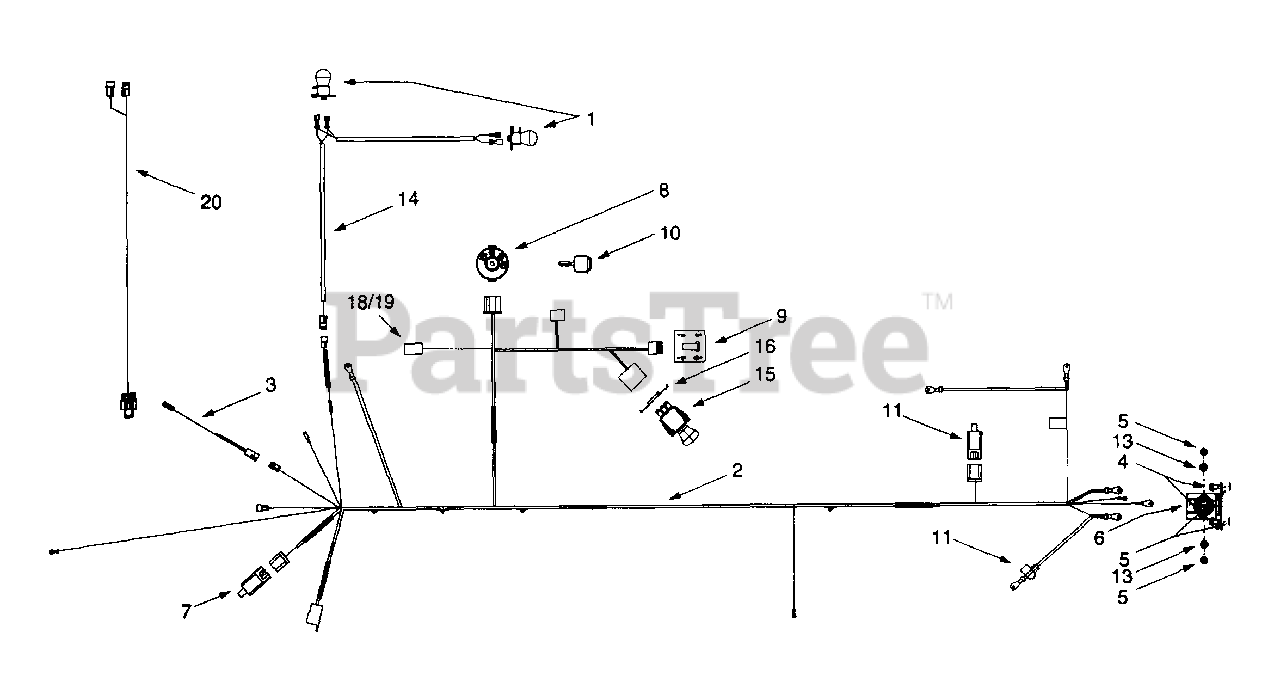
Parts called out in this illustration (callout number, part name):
1	Bulb/Socket Headlight Assembly
2	Wiring Harness w/o Ref. 14
3	Harness Adapter, #18 x 5
4	Self Tapping Screw, 1/4-20 x .5
5	Hex Nut, 1/4-20
6	Solenoid, 12-volt, 100 Amp
7	Snap Mount Safety Interlock Switch
8	Ignition Switch
9	Systems Indicator Monitor w/ Hour Meter
10	Ignition Key
11	Safety Plunger Switch (Seat)
13	Lock Washer, 1/4
14	Headlight Harness
15	Electric PTO Switch
16	Retainer Bracket
18	Fuse Holder
19	20-amp Fuse
20	Harness Adapter
